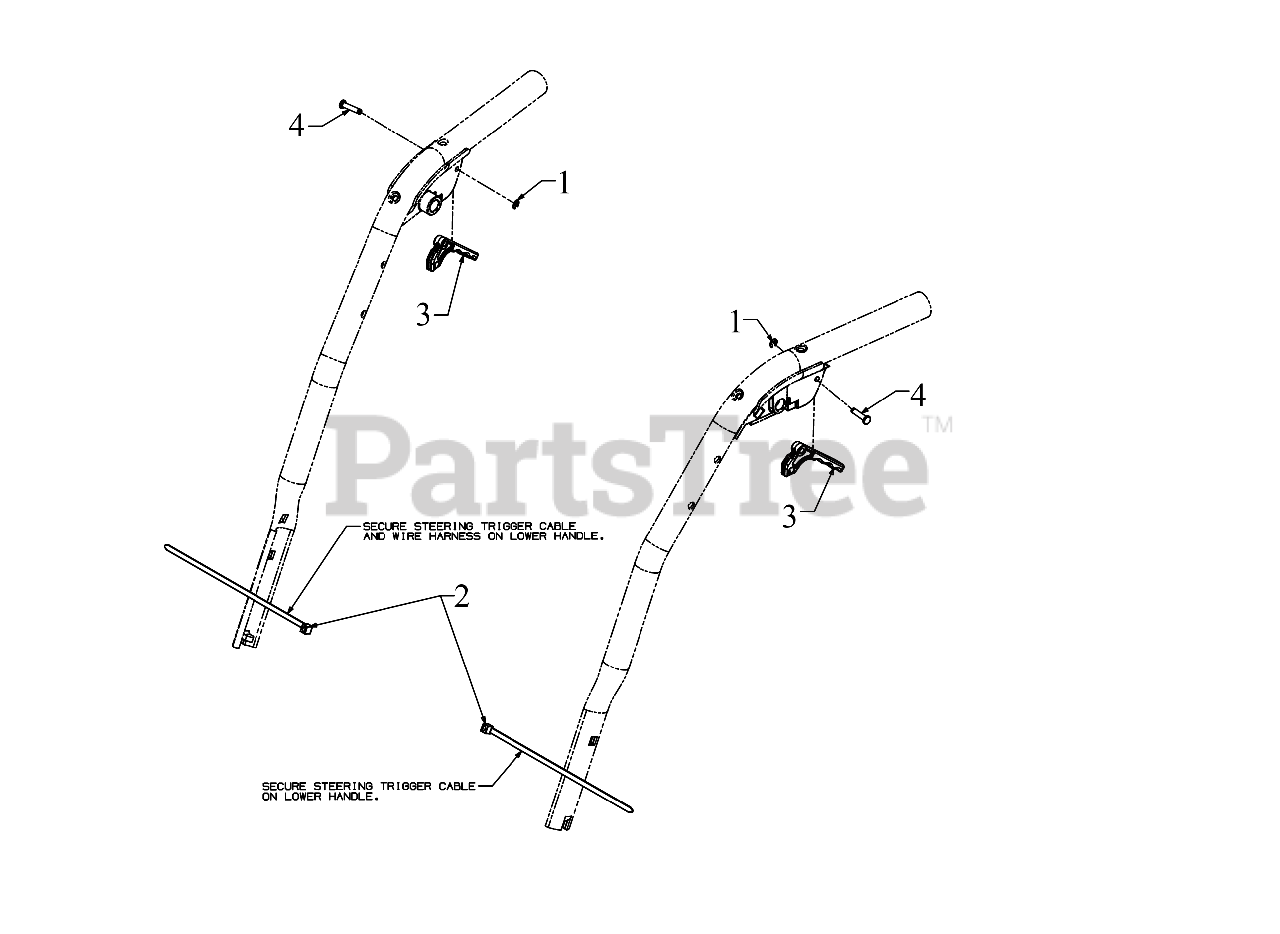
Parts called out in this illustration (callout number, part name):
2	7" CABLE TIE
3	TRIGGER YELLOW
4	STEERING TRIGGER PIN 3/16
